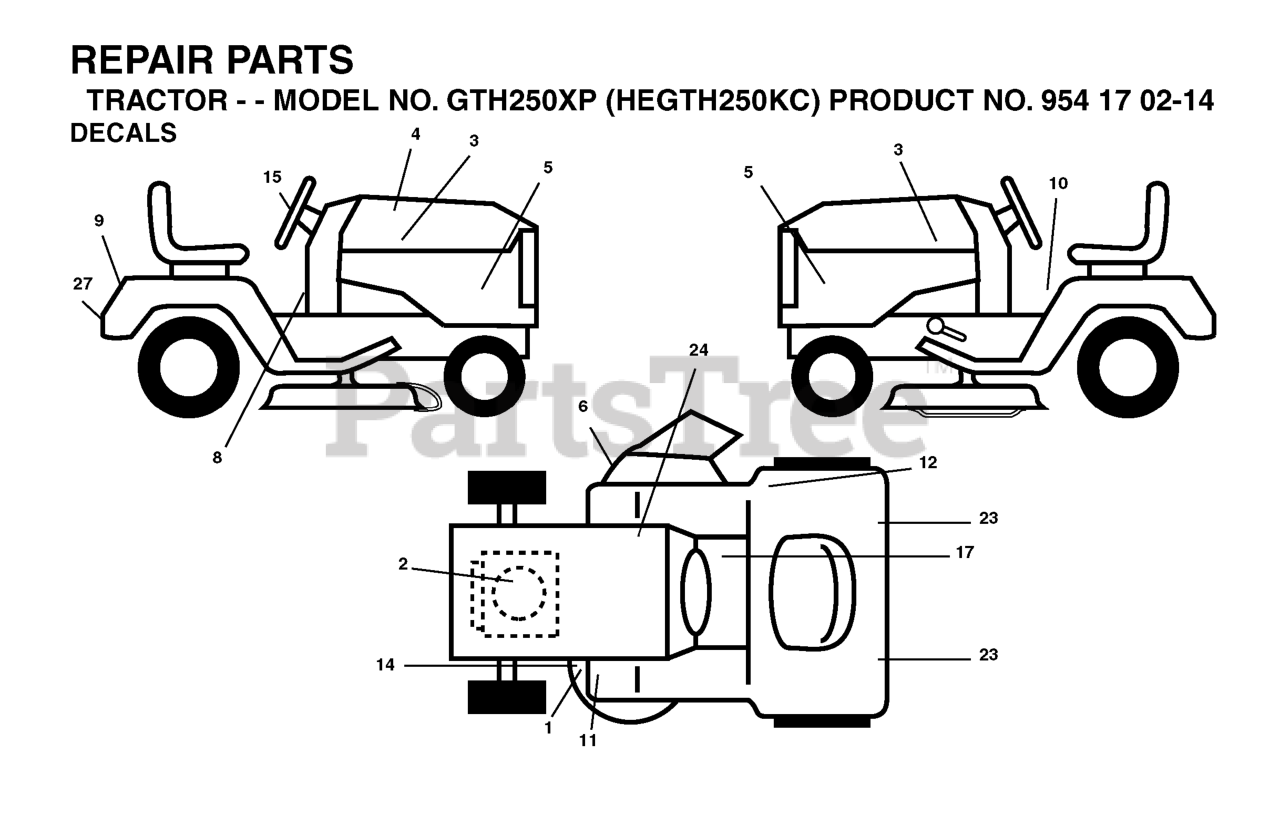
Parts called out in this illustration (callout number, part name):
1	LEVER.CONTROL.RH.PNT
2	LEVER.CONTROL.LH.PNT
5	SPRING RETAINER
7	BAIL.CONTROL.INTERLOCK
8	ARM,IMPELLER ROD
9	ARM.TRACTION.ROD.YZ
10	PANEL.CONTROL.PNT.BLACK
11	HEX BOLT
12	BOLT.FIN.HEX.5/16-18X3/4
13	TUBE.HANDLE.PLOW.LH.PNT
14	TUBE.HANDLE.PLOW.RH.PNT
15	NUT.LOCK.5/16-18
16	WASHER
17	KNOB.HANDLE.3/8.TRI-POINT.BLAC
18	ROD.ASM.IMPELLER
19	ROD.ASM.TRACTION
22	BOLT 3/8-16 X 2-1/4
23	TUBE.LOWER.HANDLE.24.BLACK
24	SLEEVE, SPRING
25	SPRING, TRACTION DRIVE
26	SPRING, AUGER CONTROL
27	SCREW 3/8-16X1
28	SPACER CONTROL LEVER
29	Screw, Grounding
30	CONSOLE, PANEL
31	SCREW, HEX HD TAPPING #10-24 1
32	SCREW, HEX HEAD, TAPPING
34	SCREW 14-20 X 5/8
36	RP SPRING, TORSION
37	SPRING.INTERLOCK
38	HEADLIGHT.HALOGEN.SNOW
39	BEZEL.HEADLIGHT.BLACK
40	HARNESS.WIRE.LIGHT/GRIP.SNOW
41	RIVET.POP.1/8X
42	CAM.INTERLOCK.RELEASE
47	BRKT.PANEL.RH.INT
48	BRKT.PANEL.LH.INT
49	GRIP.HANDLE.HEATED
50	SWITCH.GRIP.HEATED
